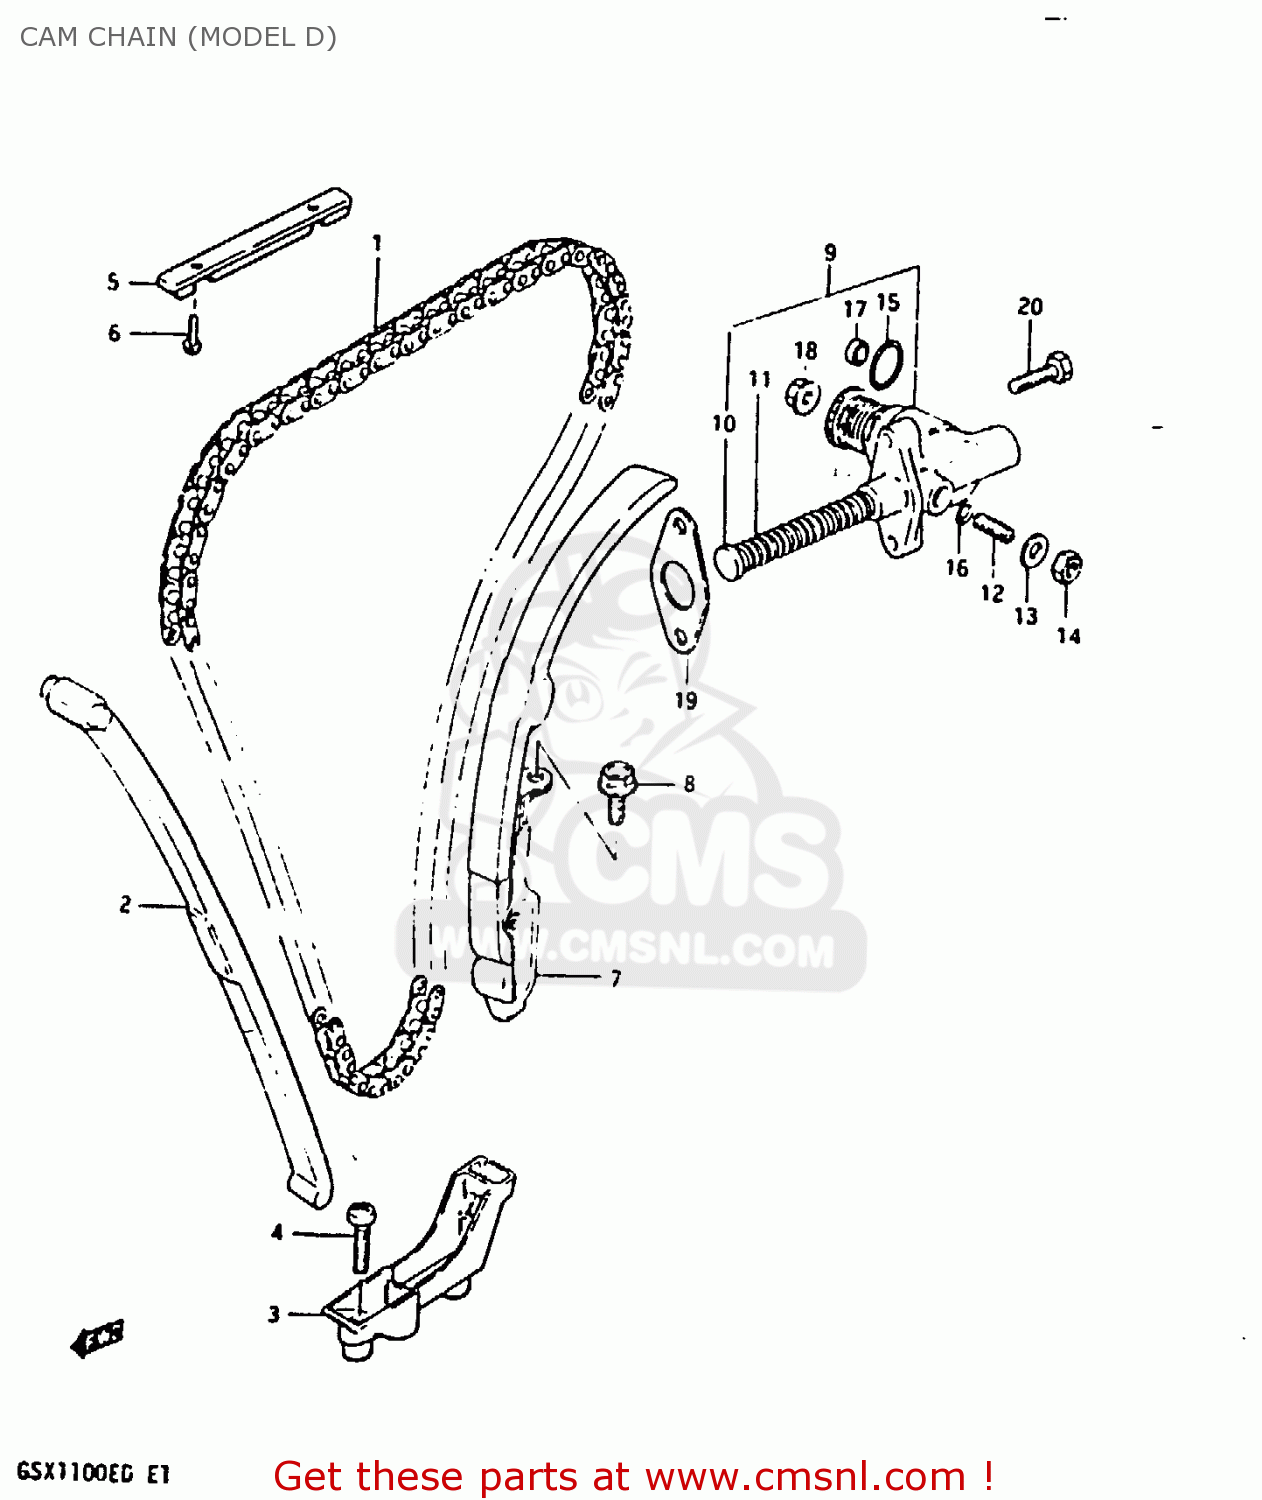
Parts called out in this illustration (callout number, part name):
1	CHAIN,CAMSHAFT DRIVE
2	GUIDE,CAM CHAIN NO.1
3	HOLDER,CAM CHAIN GUIDE
4	SCREW
5	GUIDE,CAM CHAIN
6	SCREW
7	TENSIONER,CAM CHAIN
8	BOLT
9	ADJUSTER ASSEMBLY,TENSIONER
10	ROD,PUSH
11	SPRING
12	SCREW,TENSIONER ADJUST
13	WASHER,8.5X16X
14	NUT
15	O-RING
16	O-RING
17	OIL SEAL
18	NUT
19	GASKET,TENSIONER ADJUSTER (MCA)
20	SCREW
